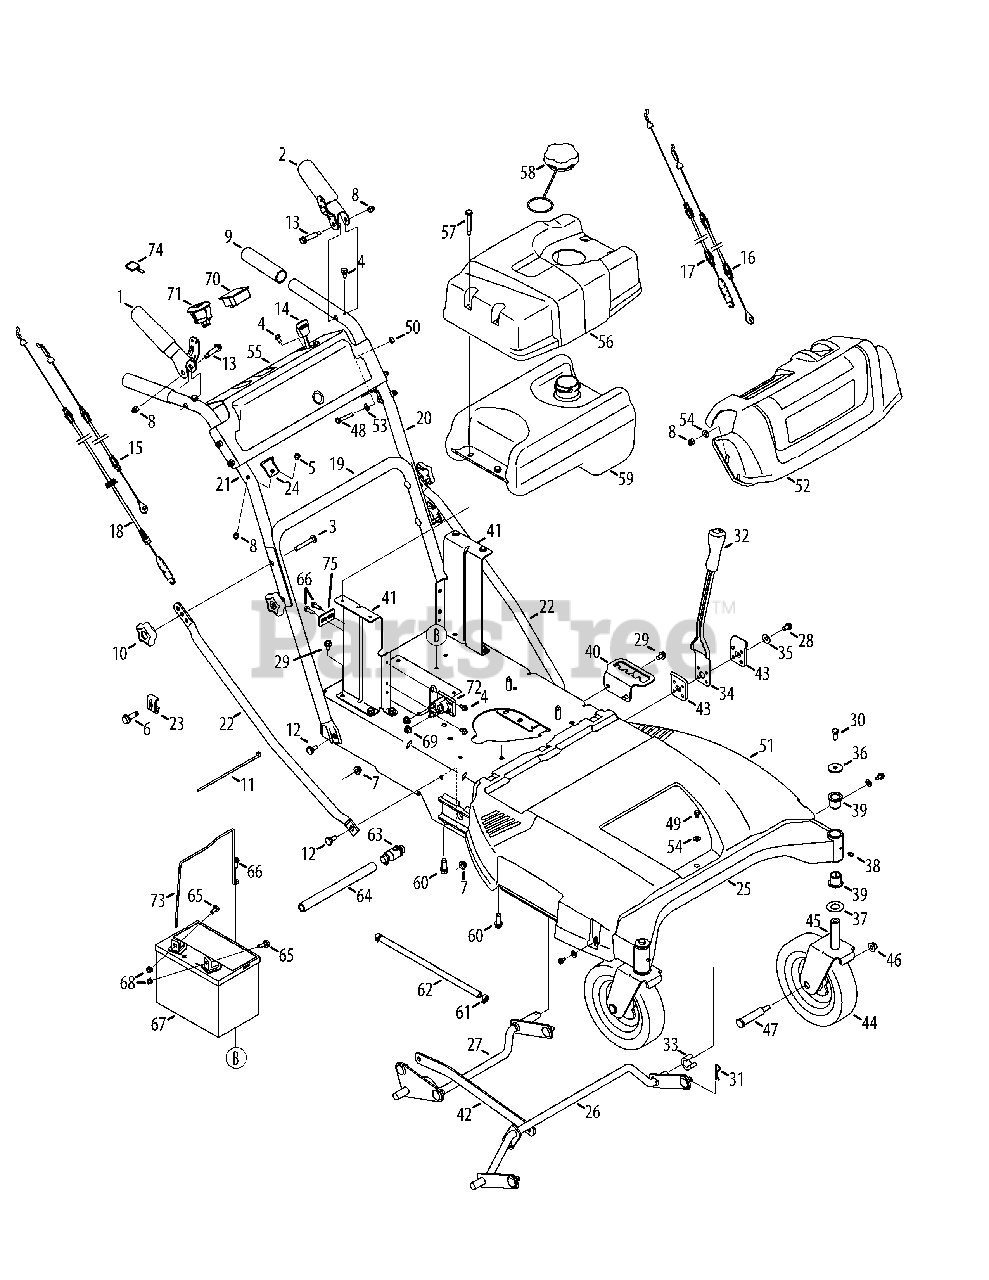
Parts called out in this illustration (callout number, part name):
1	RH Lever Assembly Bracket
2	LH Lever Assembly Bracket
3	Screw, Carriage, 5/16-18 x 2.25
4	Screw, 1/4-20 x 0.500
5	Hex Screw, 1/4-20 x 1.50
6	Screw, #10-32 x 0.625
7	Nut, Flangelock, 5/16-18
8	Lock Nut Cap, 1/4-20
9	Grip, 1.0 ID x 5.0 LG
10	Star Knob, 5/16-18
11	Cable Tie, 3/16 x .05 x 7.4
12	Screw, Shoulder, .435 x .178-5/16 x .56
13	Screw, Shoulder, .375 x 1.355 x 1/4-20
14	Throttle/Choke Cable, 38.0 x 1.1 EXT
15	RH Brake Cable, Tecumseh Trans.
16	LH Brake Cable, Tecumseh Trans.
17	Wheel Clutch Cable
18	Deck Clutch Cable
20	Upper LH Handle
21	Upper RH Handle
22	Adjustable Handle Brace
23	Casing Clamp
24	RH Cable Mount Bracket
24	LH Cable Mount Bracket
25	Frame Assembly
26	Front Deck Lift Assembly
27	Rear Deck Lift Assembly
28	Hex Screw, 5/16-18 x .50
29	Screw, 5/16-18 x 0.625
30	Hex Screw, 5/16-24 x .750
31	Click Pin, .092 x 1.64 LG
32	Grip Handle, 1/2
33	Plastic Spacer, .63 ID x .75 LG
34	Deck Height Lever
35	Washer, Bell, .340 x .872 x .060
36	Washer, Flat, .330 x 1.25 x .120
37	Washer, Flat, .760 ID x 1.50 OD
38	Drive Lube Fitting, 3/16
39	Flange Bearing, .760 x .941 x 1.0
40	Height Adjustment Bracket
41	Fuel Tank Mount Bracket
42	Link Pivot Bracket
43	Lever Pivot Bracket
44	Caster, Wheel, 8 x 1.75
44	Bearing, Flange w/ftg
45	Wheel Caster Bracket
46	Nut, Flangelock, 3/8-16
47	Bolt, Shoulder, .625 x 2.515 x 3/8-16
48	Hex Screw, 1/4-20 x 1.75
49	Screw, 1/4-14 x 0.625
50	Nut, Hex, 1/4-20
51	Belt Cover
52	Handle Panel, Black
53	Washer, Bell, .265 x .75 x .062
54	Washer, Flat, .25 x .630 x .0515
56	Fuel Tank Cover
57	Screw, Shoulder, 1/4-20 x .32 x 1.8
59	Fuel Tank
60	Screw, 3/8-16 x 1.250
61	Hose Clamp, .490 DIA.
62	Fuel Hose, Low Permeation, 1/4
64	Extension Hose
65	Hex Head Flange, 1/4-20 x .75
66	Screw, 1/4-20 x 0.750
68	Sems Nut, 1/4-20
69	Nut, Flangelock, 1/4-20
71	Key Switch
72	Solenoid, 12V, 100 AMP
73	Battery Hold Down Strap
75	Plate, Shift
